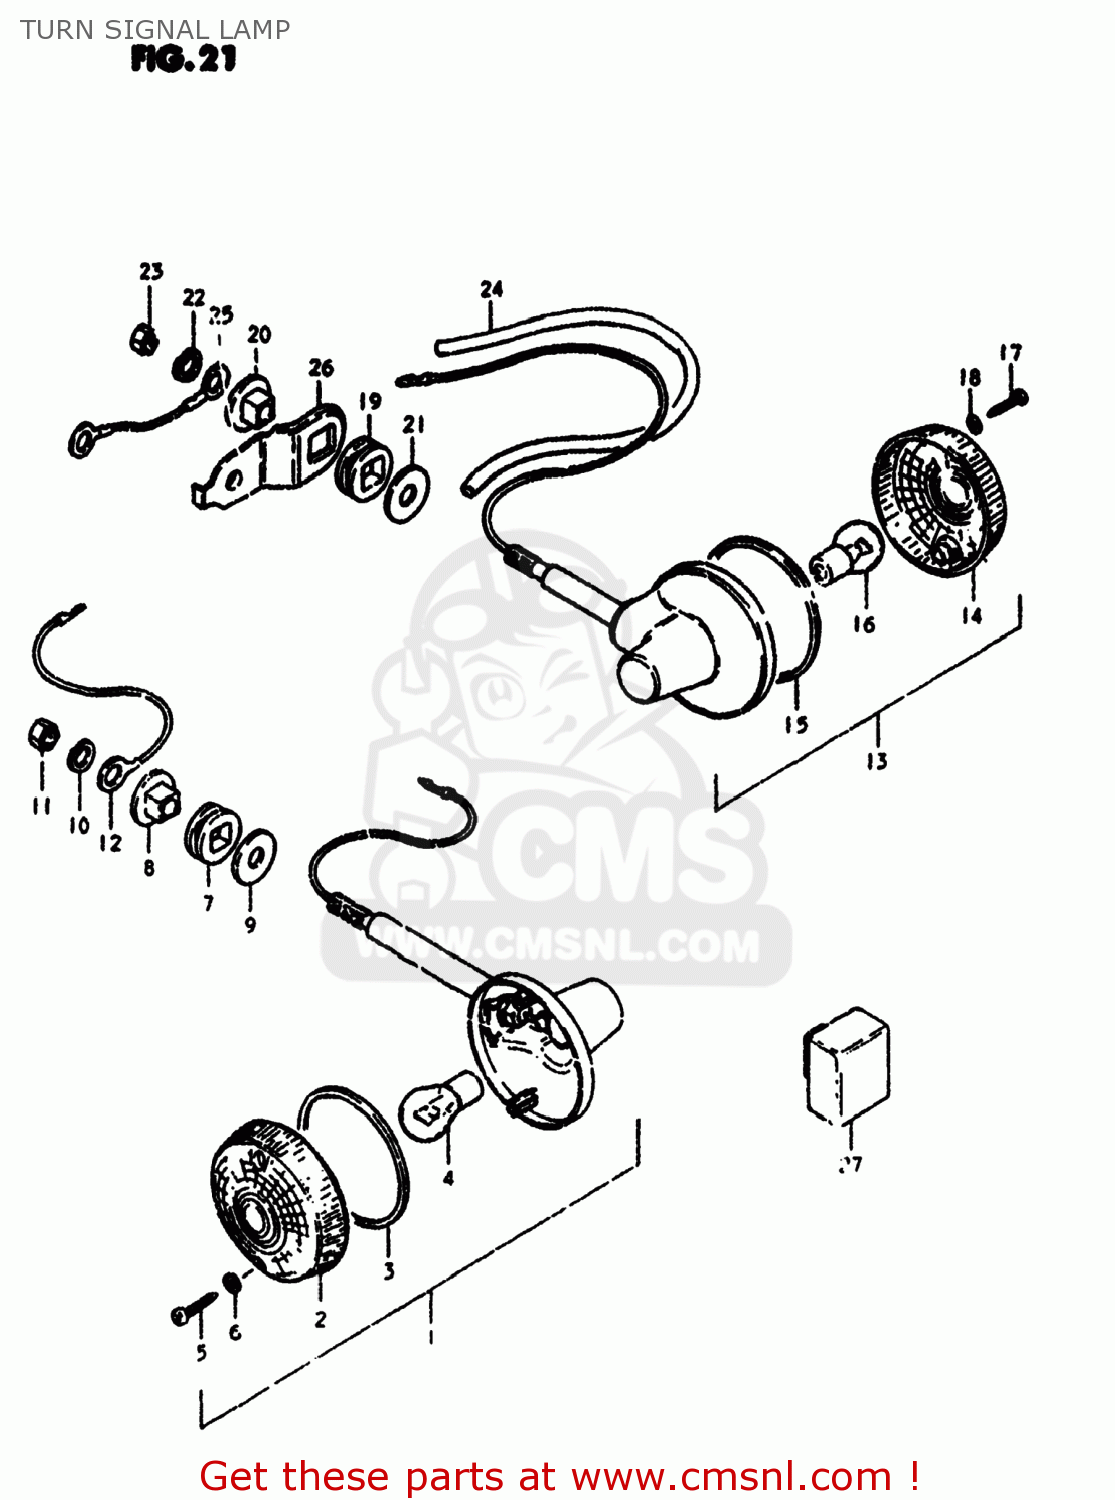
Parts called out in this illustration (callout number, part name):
1	LAMP ASSEMBLY,FRONT TURN SIGNAL
2	LENS
3	GASKET (NAS)
4	BULB(6V17W,STANLEY,A4513A)
5	SCREW
6	GASKET (NAS)
7	CUSHION
8	SPACER,TURN SIGNAL LAMP
9	WASHER (10.5X30X2.3)
10	LOCK WASHER
11	NUT
12	LEAD WIRE,EARTH
13	LAMP ASSEMBLY,REAR TURN SIGNAL
14	LENS
15	GASKET (NAS)
16	BULB(6V17W,STANLEY,A4513A)
17	SCREW
18	GASKET (NAS)
19	CUSHION
20	SPACER,TURN SIGNAL LAMP
21	WASHER (10.5X30X2.3)
22	LOCK WASHER
23	NUT
24	PROTECTOR, LEAD WIRE
25	LEAD WIRE,EARTH
26	BRACKET,REAR TURN SIGNAL
27	RELAY,TURN SIGNAL
